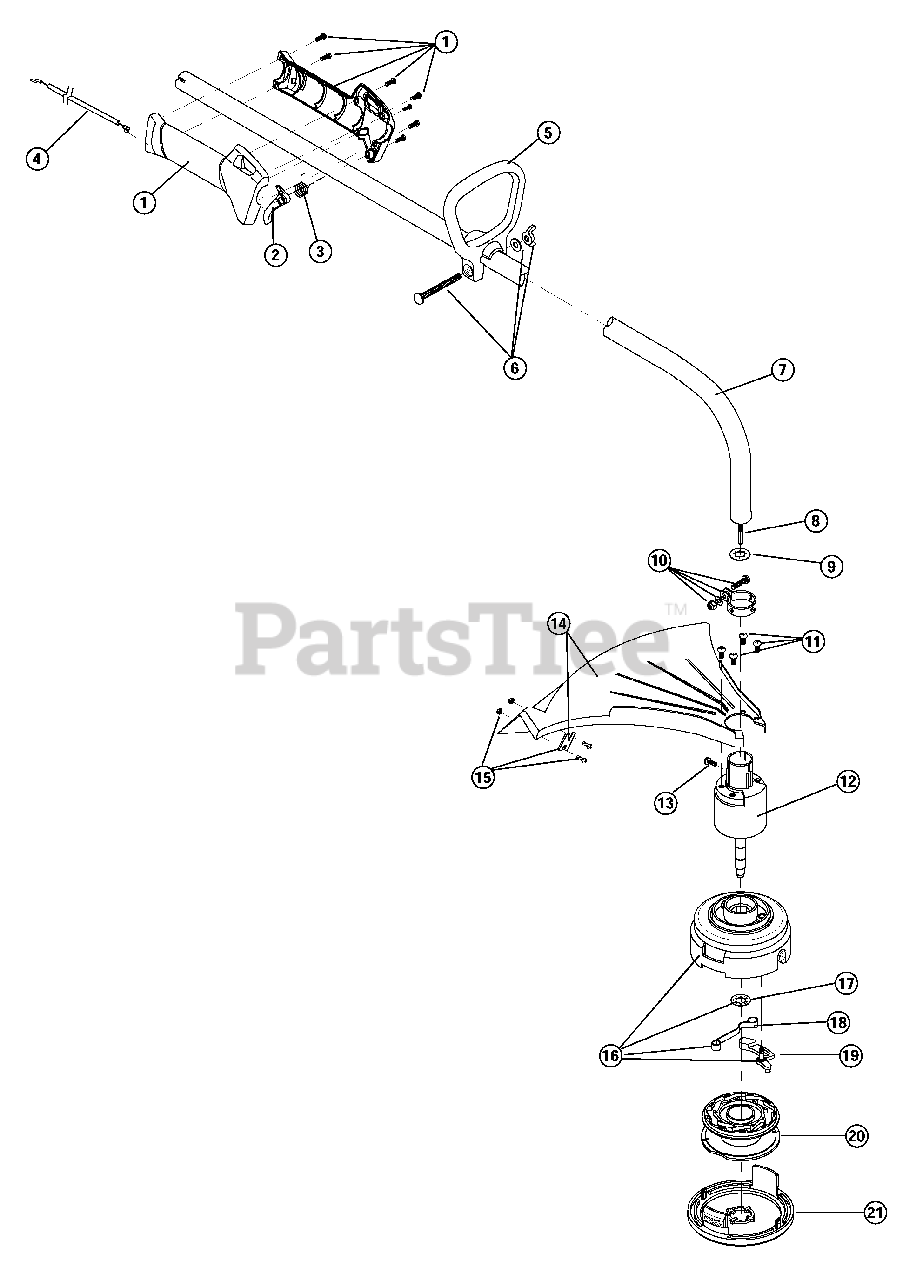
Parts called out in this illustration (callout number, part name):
1	Throttle Housing & Trigger Assembly (includes 2 & 3)
2	Throttle Trigger Spring
3	Throttle Trigger
4	Throttle Cable Assembly
5	D-Handle Assembly (includes 6)
6	D-Handle Hardware
7	Drive Shaft Housing Assembly
8	Flexible Drive Shaft
9	Palnut
10	Lower Clamp Assembly
11	Shield Mounting Screw
12	Bushing Housing Assembly w/shaft (For ALF Head)
12	Housing
13	Anti-Rotation Screw
14	Shield and Blade Assembly (includes 15)
15	Blade Assembly
16	Outer Spool w/ Retainer (includes 17-19)
17	Retainer
18	Pawl Spring
19	Ratchet Pawl
20	Inner Reel
21	Spool Cover
